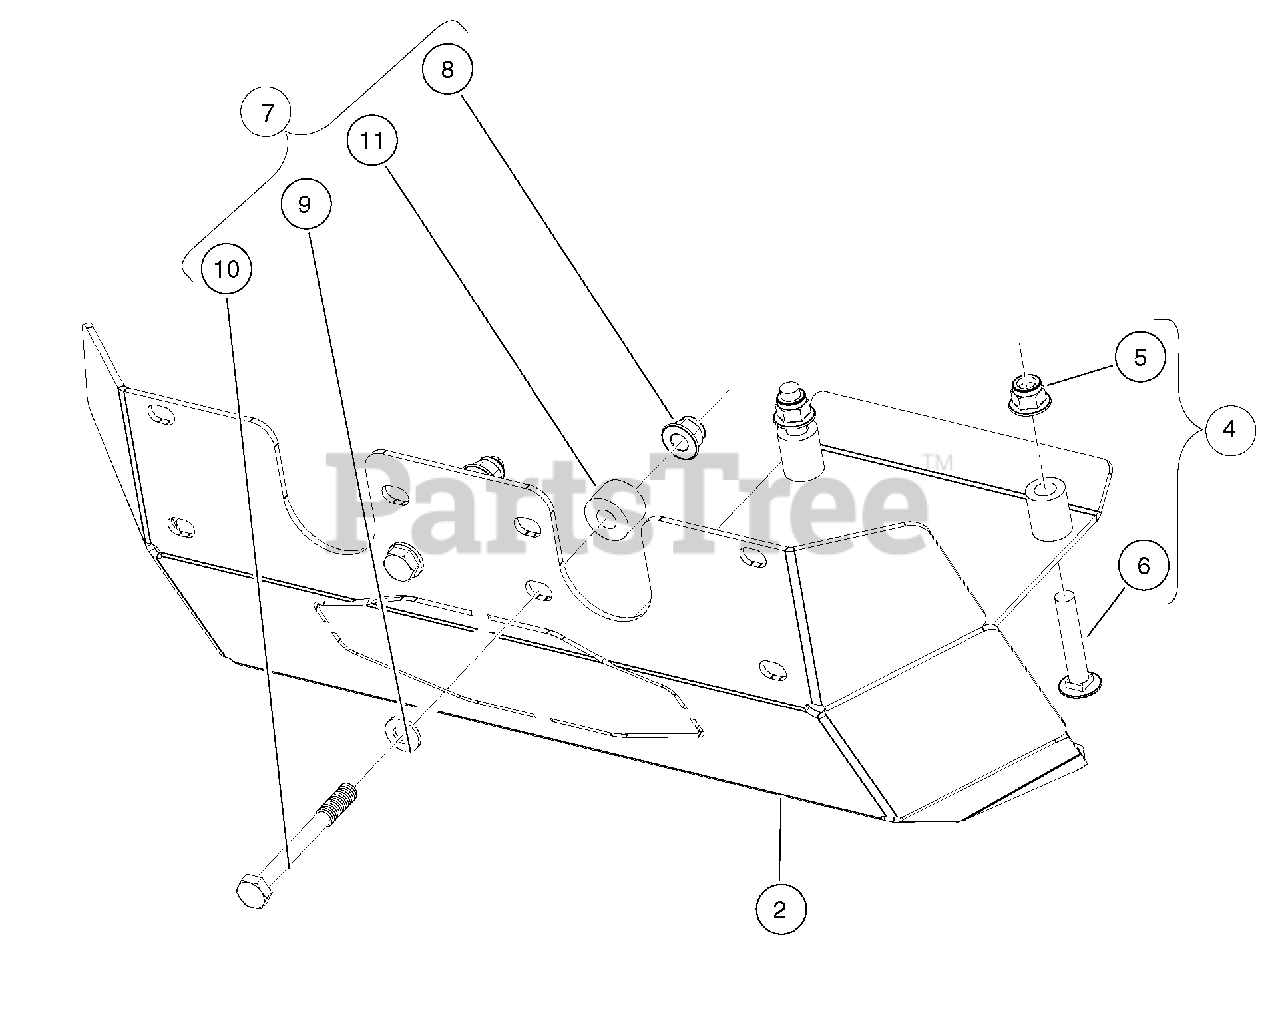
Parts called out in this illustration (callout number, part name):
1	Kit, Skidplate, Front, Steel
2	Skid Plate, Front, Steel
3	Instructions, Front Skidplate
4	Kit, Hardware, Skidplate, Front, A
5	Nut Flg M10 X 1.5 Nylon
6	Bolt, Carriage, M10x1.5x55
7	Kit, Hardware, Skidplate, Front, B
8	Nut Flg M10 X 1.5 Nylon
9	Washer, Hard, M10, Zn-Ni/Blk
10	Bolt, M10 X 1.50 X 90, Loctite
11	Spacer, 17mm Long, Skidplate
